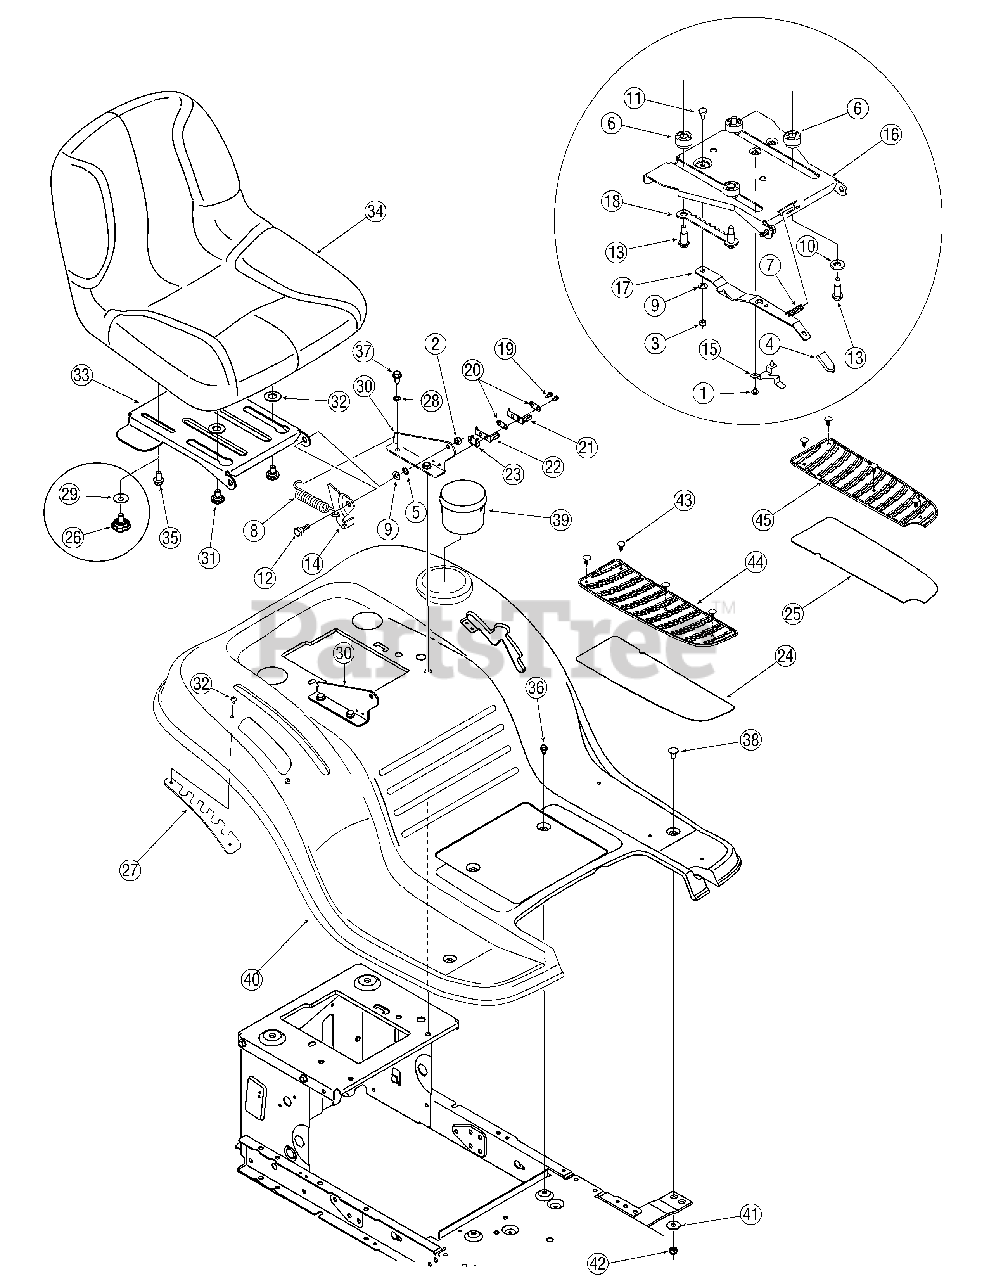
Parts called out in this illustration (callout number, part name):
1	Screw, #10-16, .375
2	Nut, Flange Lock, 5/16-18, GrF, Nylon
3	Nut, Flange Lock, 1/4-20
4	Seat Adjuster Grip
5	Nut, Speed, .3125 ID
6	Spacer
7	Compression Spring, .41 x 1.5
8	Spring, Extension, .84 Dia. x 4.6
9	Wash, Flat, .344 x .688 x .065
10	Wash, Flat, .531x 1.062 x.134
11	Screw, Shoulder, .340 x .285,1/4-20
12	Screw, Shoulder, .437 x .268, 5/16-18
13	Screw, Shoulder, .50 x .925, 3/8-16
14	Seat Bracket, Lift
15	Seat Stop
18	Seat Adjustment Selector
19	Screw, #8-18 x .50
20	Plate, Insulator
21	Spring Switch, Inner
22	Spring Switch, Outer
23	Plate, Insulator Boss
24	Foot Pad, Abrasive, RH
25	Foot Pad, Abrasive, LH
26	Knob, 3/8-16, .875
28	Lock Washer 5/16
29	Washer, Flat, .406 x 1.00 x .030
31	Screw, Shoulder, .625 x .175, 3/8-16
32	Screw 1/4-20, 0.500
34	Seat, Low Back
34	Seat, Medium Back
35	Screw, 3/8-16, .625
36	Screw, 1/4-20, 0.500
37	Screw, 5/16-18, 0.625
38	Screw, Carriage, 3/8-16, .875 Gr5 STD
39	Cup Holder
41	Washer, Flat, .28 x .74 x .063
42	Nut, Flange Lock, 1/4-20, GrF, Nylon
43	Clip, Ratchet, .250 Dia
44	Foot Pad, RH
45	Foot Pad, LH
